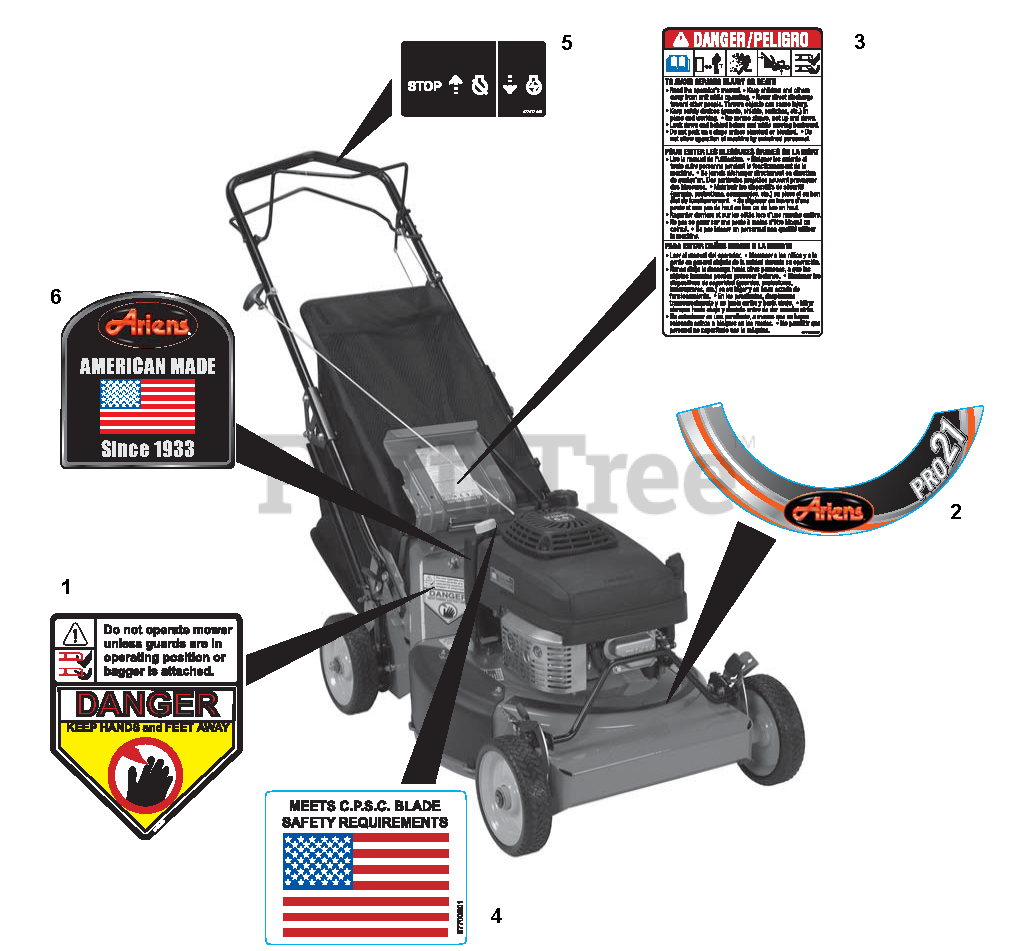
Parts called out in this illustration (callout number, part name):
1	DECAL, CPSC DANGER
2	DECAL, ARIENS PRO21 DECK
3	DECAL, BILINGUAL DANGER
4	DECAL, CPSC/USA FLAG
5	DECAL, MADE IN AMERICA(ARIENS)
6	DECAL - ENGINE CONTROL
